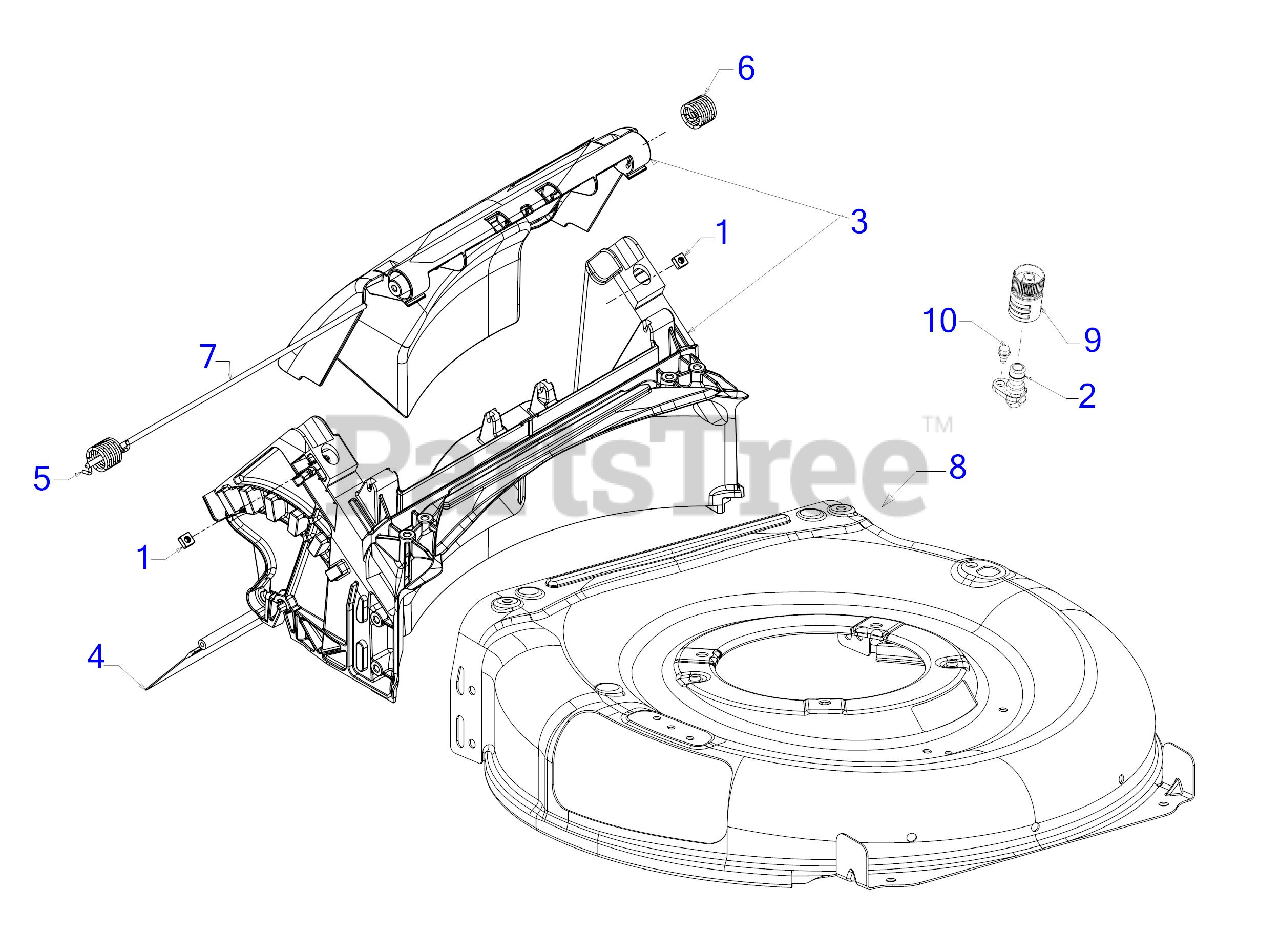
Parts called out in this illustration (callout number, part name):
1	SQUARE NUT 1/4-20
2	DECK WASH NOZZLE
3	REAR BAG DOOR ASSEMBLY
4	TRAILSHIELD
5	TORSION SPRING (RH)
6	TORSION SPRING (LH)
7	REAR DOOR PIVOT ROD
9	WATER NOZZLE
10	SHOULDER SCREW 1/4-20 x .50
